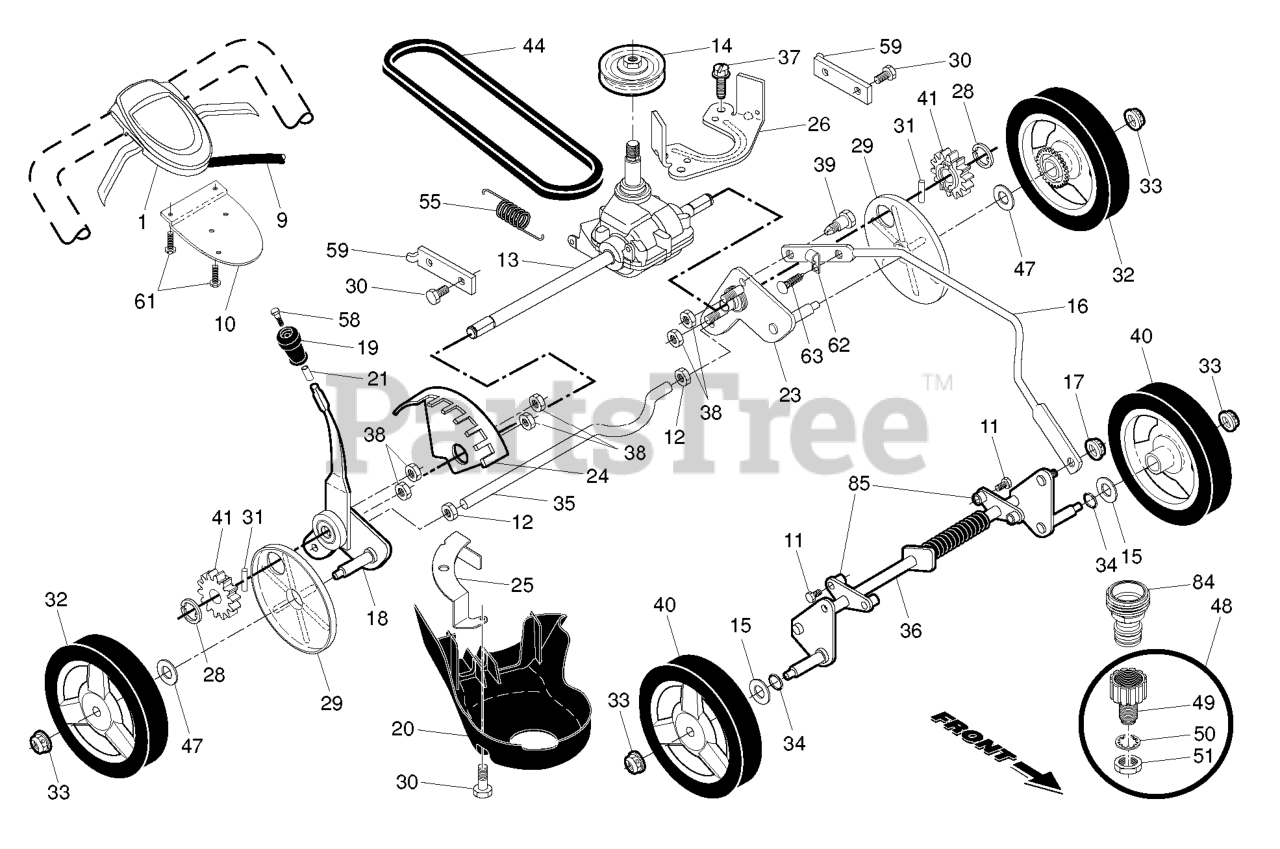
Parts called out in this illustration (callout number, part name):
1	RP CONTROL AW2 22+RGD KH GY/BL
9	CABLE.CONTROL.22RGD.GEN2
10	BRACKET.DRIVE.CONTR.GEN2.BLACK
11	SCREW.HX.13X.750
12	NUT.HEX.1/2-20
13	RP TRANSMISSION.22+.RGD.AW2/
15	WASHER.FLAT.1/2
16	ROD.CONNECTING.RGD.22+.HW.BLAC
17	NUT.LOCK.5/16-18
18	KIT.SELECTOR.ASM.437869
19	KNOB.SEL.SPRING.22+.SP.RIB.BLK
20	COVER.BELT.22.RGD
21	SCREW.PLASTIC.ANCHOR.5/16
23	ADJUSTER.ARM.ASM.AX.RT.SP.ZC
24	BRACKET.WHL.ADJ.9.POS.W/PAD
25	BRACKET.DRIVE.COVER.RGD.BZP
26	BRACKET.TRANS.BELT.KEEPER.BZP
28	E-RING 7/16 RE
29	COVER.DUST.WHEEL
30	BOLT.5/16HEX.WHS.HD
31	PAWL, DRIVE
32	KIT.WHEEL.442789X460.8"
33	NUT.HEX.FLANGE.3/8-16.LO(3 2)
34	O-RING..070X.487.NEOPRENE
35	AXLE.REAR.RGD
36	AXLE.ASM.FRONT.RGD.CLEAR.ZINC
38	NUT.HEX.FLANGE.1/4
39	SHOULDER BOLT SEMI GIMLET PT.
40	WHEEL.8IN.H3SPK.ALPHA.
41	PINIION.14.TOOTH.RGD
44	BELT.DRIVE.RGD.PLUS
47	WASHER FLUT
48	KIT.WASH-OUT.PORT.ZINC.WALK
49	WASHOUT.PORT.ZINC.RGD.22+
50	WASHER.LOCK.INTERNAL.TOOTH
51	LOCKNUT.HEX.WITH.O-RING
58	SCREW.12-14X1.500
59	BRACKET.SUPPORT.22+RWGD.BZP
61	SCREW, PHILLIPS HEAD 10 X 5/8
62	CLIP.CABLE.BLK
63	FASTENER.PUSH.O.250X0.783
84	COUPLING.QUICK CONNECT
85	BRACKET.FRT.AXLE.SUPPORT
